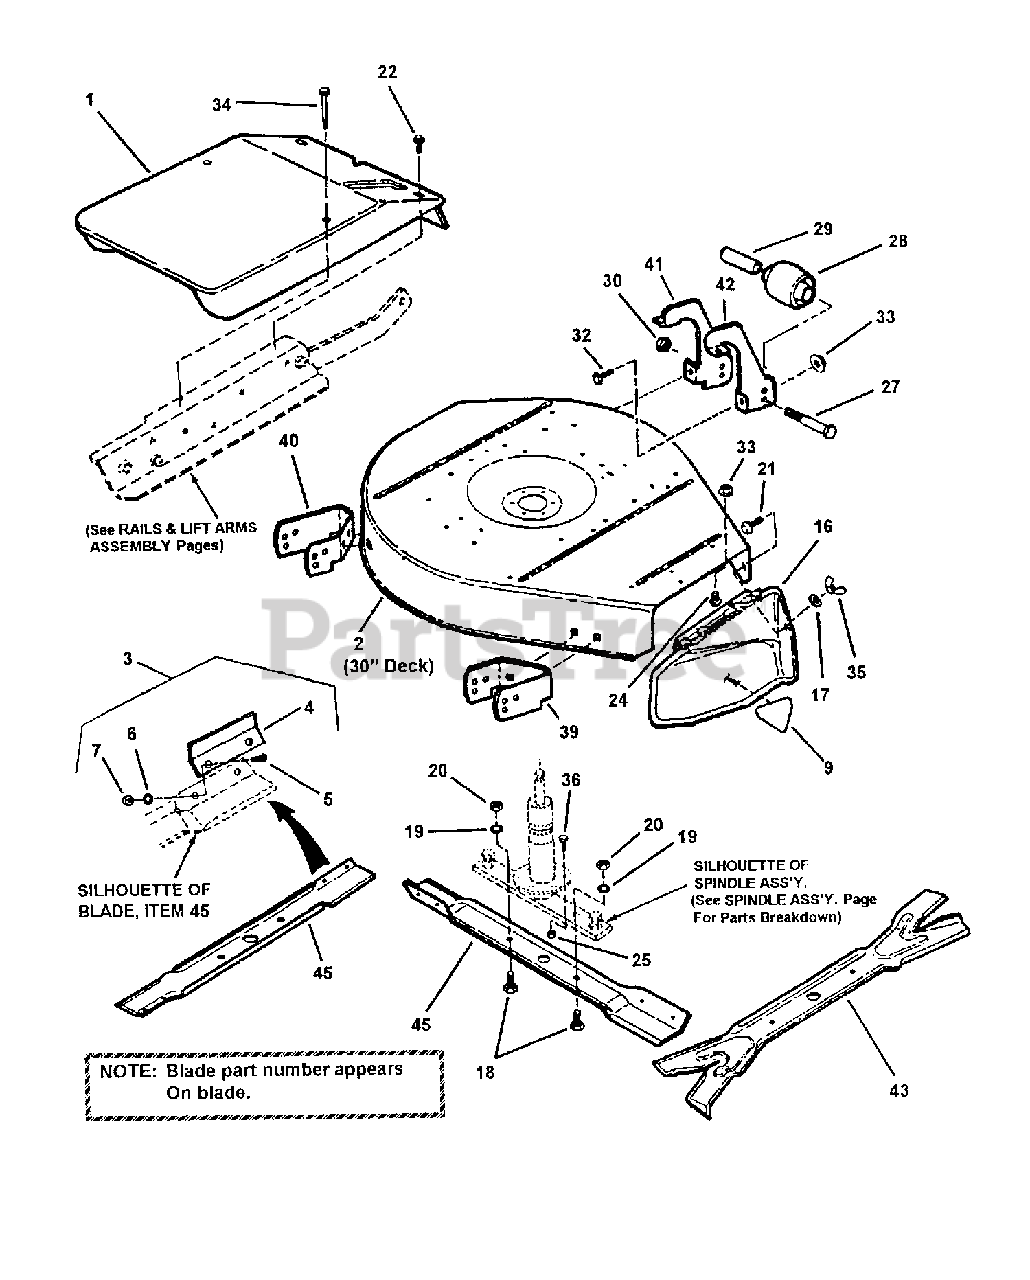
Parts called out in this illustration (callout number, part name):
1	COVER, Spindle
2	DECK, 30" (Painted w/decals)
3	KIT, Air Lift (30" Models)
5	SCREW, 5/16-24 x 11/16" Machine
6	WASHER, 5/16" Internal Tooth Lock
7	NUT, 5/16-24 Hex
9	DECAL, Danger
16	DEFLECTOR, 30" Discharge
17	WASHER, 5/16" Flat
18	SCREW, 1/2-20 x 1" Hex Head Cap, Grade 5
19	WASHER, 1/2" Internal Tooth Lock
20	NUT, 1/2-20 Hex Jam
21	BOLT, 5/16-18 x 3/4" Short Neck Carriage, Grade 5
22	SCREW, 1/4-20 x 5/8" Hex Washer Self-Tap
24	BOLT, 5/16-18 x 1/2" Hex Flange Lock
25	NUT, 3/18-16 Hex Flange Lock
27	SCREW, 3/8-24 x 3-3/4" Hex Head Cap, Grade 5
28	WHEEL, Gage
29	SPACER
30	NUT, 3/8-24 Hex Nyloc
32	BOLT, 5/16-18 x 1/2" Carriage
33	NUT, 5/16-18 Hex Flange Lock
34	SCREW, 1/4-20 Hex Washer Self-Tap
35	WING-NUT, 5/16-18
36	BOLT, 3/8-16 x 3/4" Hex Flange Lock
39	BRACKET, Anti-Scalp, 30" R.H.
40	BRACKET, Anti-Scalp, 30" L.H.
41	BRACKET, Anti-Scalp, 30" L.H.
42	BRACKET, Anti-Scalp, 30" R.H.
43	BLADE, Ninja 30"
45	30" BLADE
